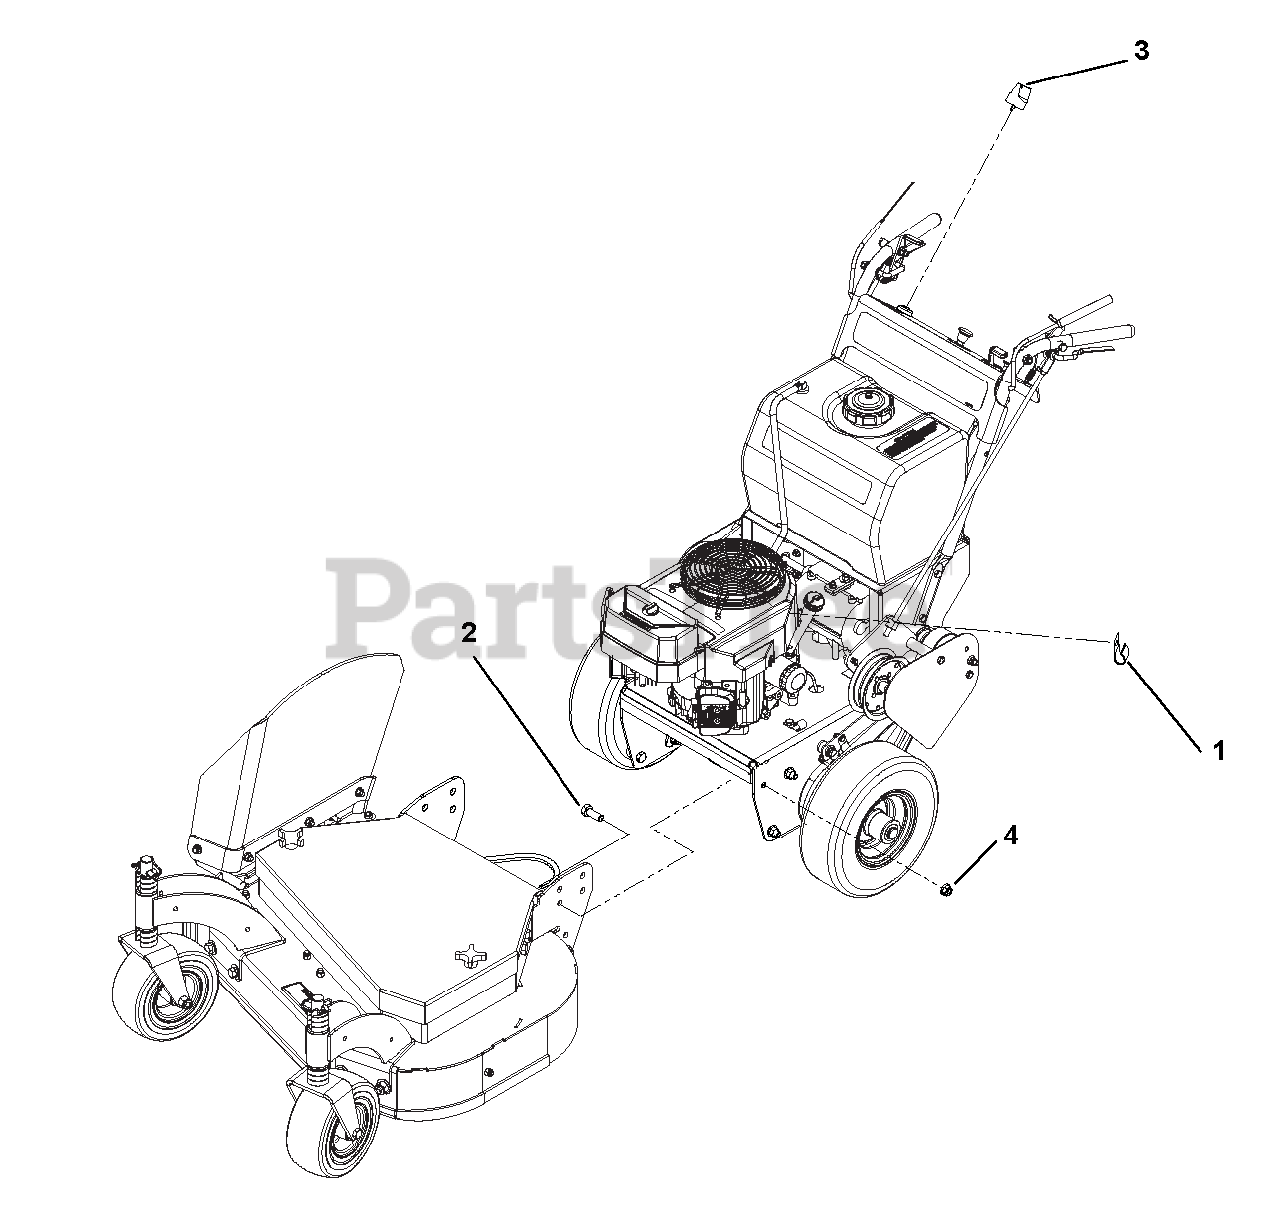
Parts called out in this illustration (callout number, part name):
1	P-CLIP, .500 INSULATED
2	BOLT, 1/2-13X1.25 HEX 5 Y
3	KEY W/ SHIELD
4	@NUT-LK-NYL-FLG .50-13 YWZC
